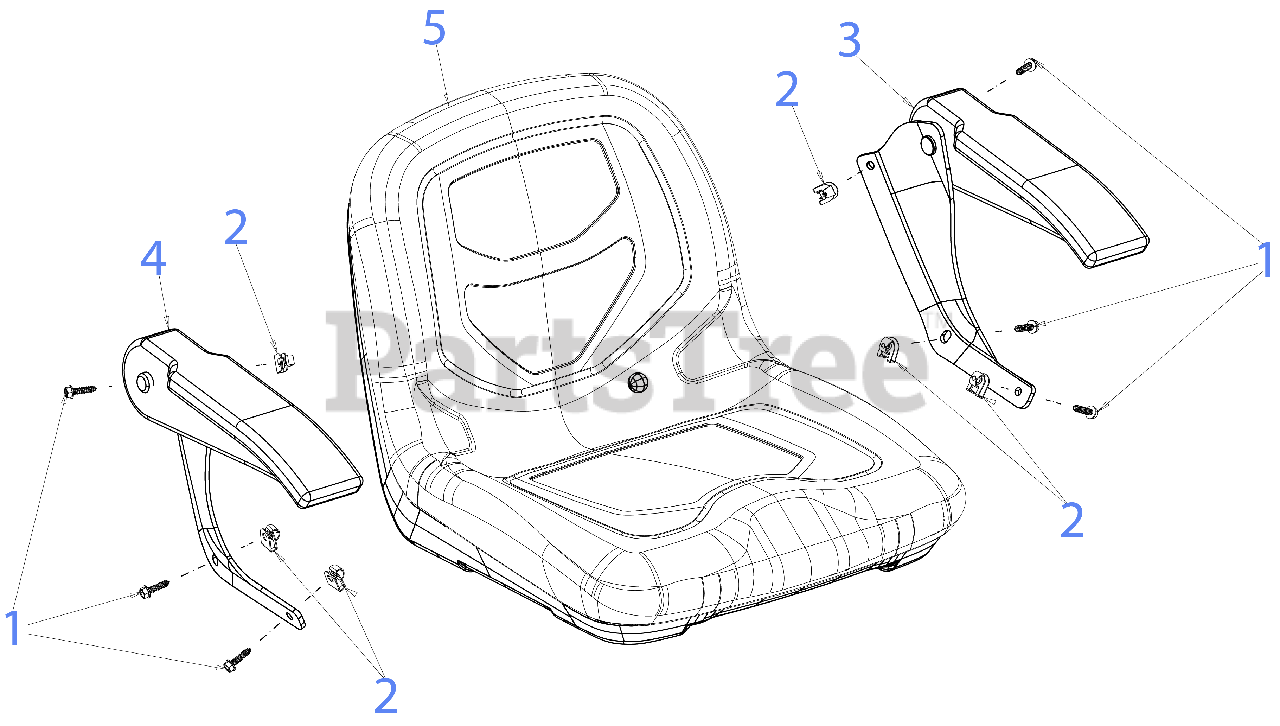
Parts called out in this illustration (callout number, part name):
1	SCREW 1/4-14X 1.00
2	ARMREST SPEED NUT
3	LH & RH ARMREST KIT
4	LH & RH ARMREST KIT
5	HI BACK SEAT (W/OPS) (BLACK)
